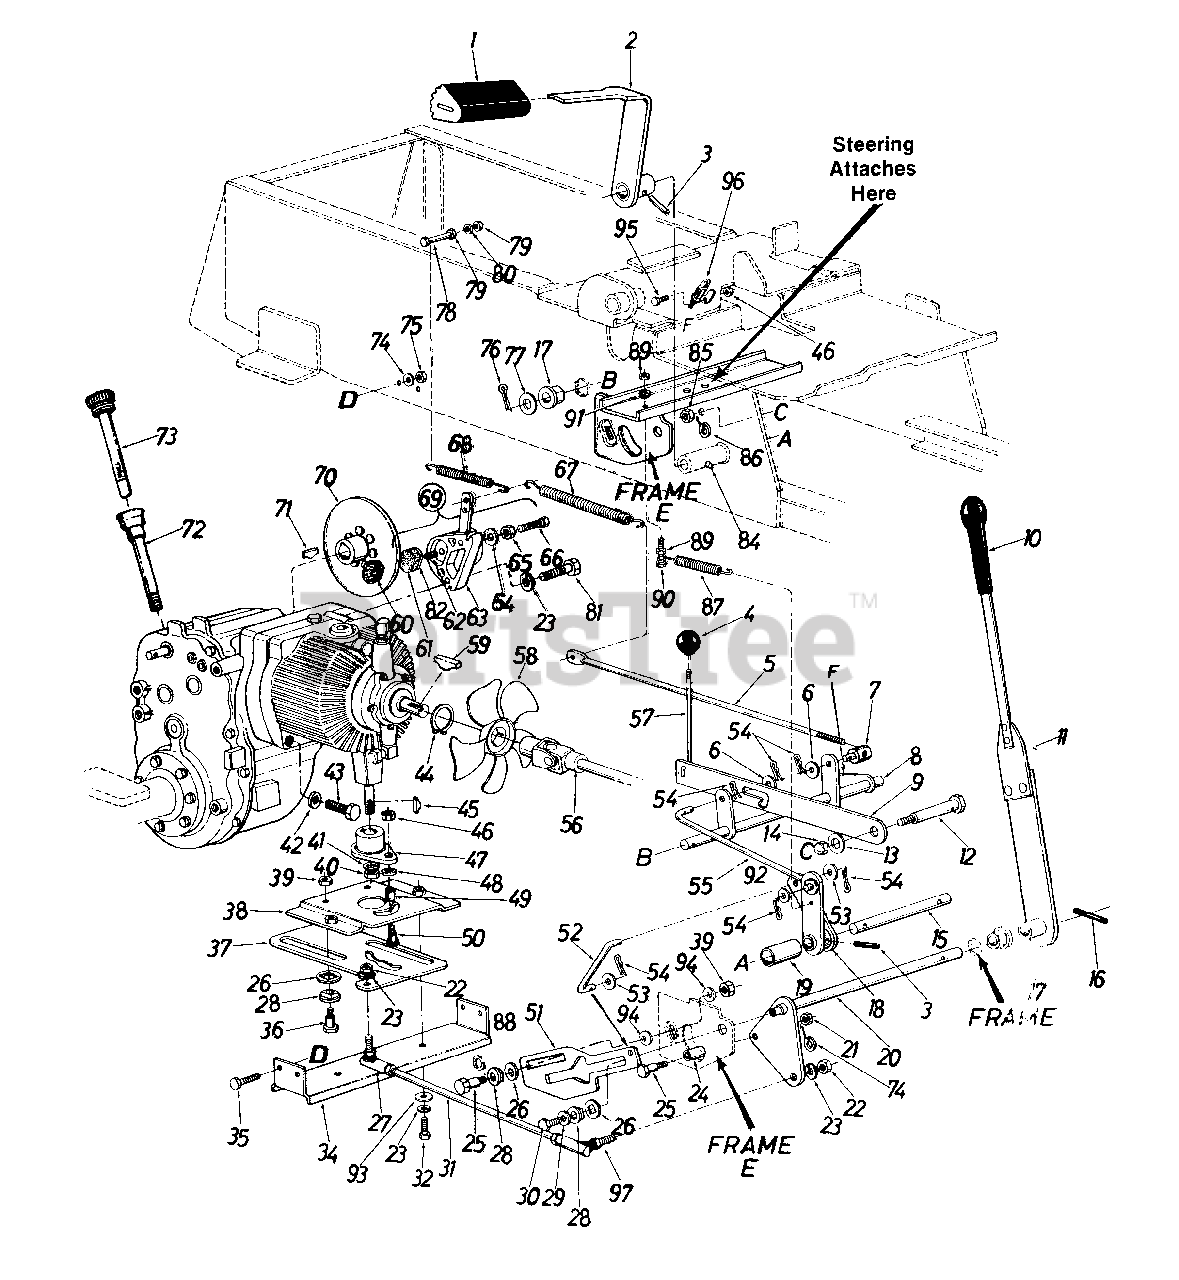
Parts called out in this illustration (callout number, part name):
1	Foot Pad
4	Ball Knob-Brake
5	Brake Rod
6	Fl-Wash. .375" I.D. x 1.00" O.D. x .030
7	Ferrule
8	Brake Transfer Shaft Ass'y.
9	Parking Brake Cam
11	Control Arm Ass'y. Comp.
12	Shld. Scr. .62 Dia. x 2.75" Lg.
13	Fl-Wash. .460 I.D. x 1.24 O.D. x .06
14	Push Speed Nut for .625 Dia. Shaft
15	Brake Pivot Shaft
16	Spring Pin Spiral 1/4" Dia. x 1.50" Lg.
17	Hex Flange Brg. Plastic .62 I.D.
18	Brake Hub Ass'y.
19	Spacer
20	Control Handle Ass'y.
21	Hex Cent. L-Nut 5/16-18 Thd.
22	Hex Nut 3/8-24 Thd.
23	L-Wash. 3/8" Scr.
24	Spacer
25	Shoulder Bolt
26	Fl-Wash. .63 Sq. Hole x 1.25" O.D.
27	Ball Joint Ass'y. 3/8-24 Thd.-L.H.
28	Pivot Slide
29	Fl-Wash. .312 I.D. x .88 O.D.
30	Hex Ins. Scr. 5/16-18 x 1.00" Lg.
31	Tie Rod
32	Hex Scr. 3/8-16 x .75" Lg.
34	Support Channel
35	Hex Scr. 5/16-18 x .75" Lg.
36	Shld. Scr. .437" Dia. x .350
37	Cam Plate
38	Slide Mtg. Plate Ass'y.
39	Hex Cent. L-Nut 5/16-18 Thd.
40	Hex Nut 1/2-13 Thd.
41	L-Wash. 1/2" Scr.
42	Fl-Wash. .385 I.D. x .87 O.D. x .060
43	Socket Hd. Scr. 3/8-16 x 2.75" Lg.
44	Snap Ring
45	#5 Hi-Pro Key 1/8" x 5/8" Dia.
46	Hex Cent. L-Nut 1/4-20 Thd.
47	Pintle Plate Ass'y.
48	Fl-Wash. .281 I.D. x .50 O.D. x .063
49	Needle Brg. .31" I.D. x .50" O.D. x .437" Lg.
50	Shld. Scr. .31 Dia. x .500 (Socket Head)
51	Neutral Control Slide
52	Neutral Control Rod
53	Fl-Wash. .312 I.D. x .630 O.D. x .063
54	Hairpin Cotter
55	Brake Link Rod Ass'y.
56	Universal Joint Ass'y. Comp.
57	Parking Brake Link
58	Fan Ass'y.
59	#61 Hi-Pro Key 3/16 x 5/8" Dia.
60	Lining-Brake
61	Lining-Brake
62	Actuator Pin
63	Housing with Lever and Pin
65	Nut
66	Adjustment Pin
67	Extension Spring .59 O.D. x 6.5" Lg.
68	Extension Spring (Brake Return)
69	Disc Brake Ass'y. Comp.
70	Brake Disc Ass'y.
71	Hi-Pro Key 3/16 x 3/4" Dia.
72	Dipstick Tube Ass'y.
73	Dipstick Ass'y.
74	L-Wash. 5/16" Scr.
75	Hex Nut 5/16-18 Thd."
76	Cotter Pin 1/8" Dia. x 1.00" Lg."
77	Fl-Wash. .635" I.D. x 1.00 O.D. x .120 Thk.
78	Hex Scr. 1/4-20 x 2.50" Lg.
79	Hex Nut 1/4-20 Thd.
80	L-Wash. 1/4" Scr.
81	Hex Scr. 3/8-16 x 1.25" Lg.
82	Backing Plate
84	Grease Fitting
85	Hex Nut 7/16-20 Thd.
86	L-Wash. 7/16" Scr.
87	Extension Spring
88	Wave Wash.
89	Hex Nut 1/4-20 Thd.
90	Hex Scr. 1/4-20 x 1.25" Lg.
91	L-Wash. 1/4" Scr.
92	Fl-Wash.
93	Fl-Wash. .38 I.D. x 1.25 O.D.
94	Bell-Wash.
95	Hex Scr. 1/4-20 x 1/2" Lg.
96	Safety Switch (Clutch)
97	Ball Joint Ass'y. 3/8-24 Thd.-R.H.
